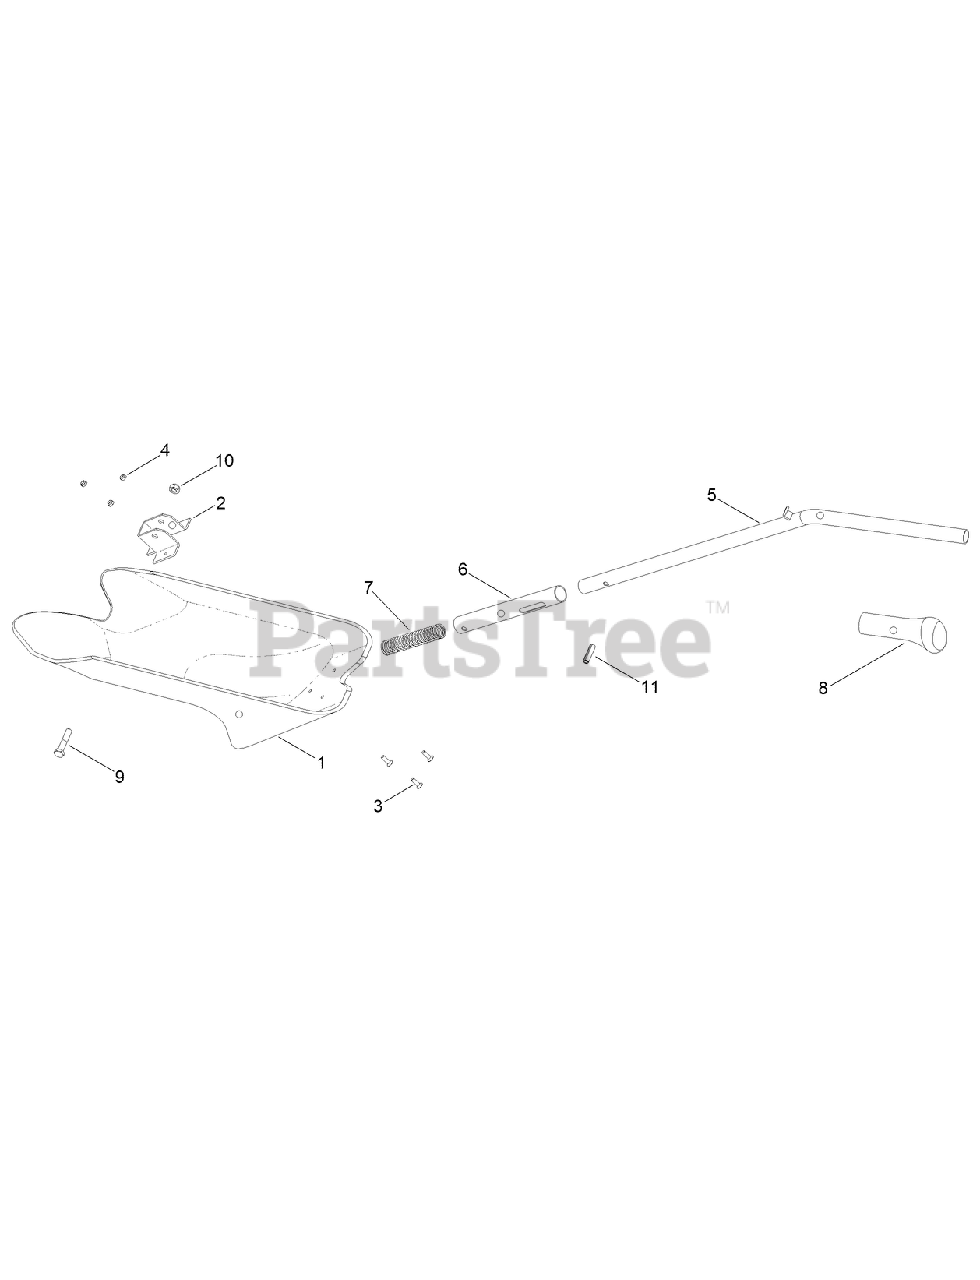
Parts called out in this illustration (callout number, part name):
1	SHIELD-MULCHING
2	BRACKET-SHIELD, MULCHING
4	NUT-LOCK
5	HANDLE-MULCHING, TOP
6	HANDLE-MULCHING, BOTTOM
7	SPRING, MULCHING
8	HANDLE-MULCHING
9	SCREW-HH
10	NUT-LOCK, NI
11	PIN-SPIRAL
